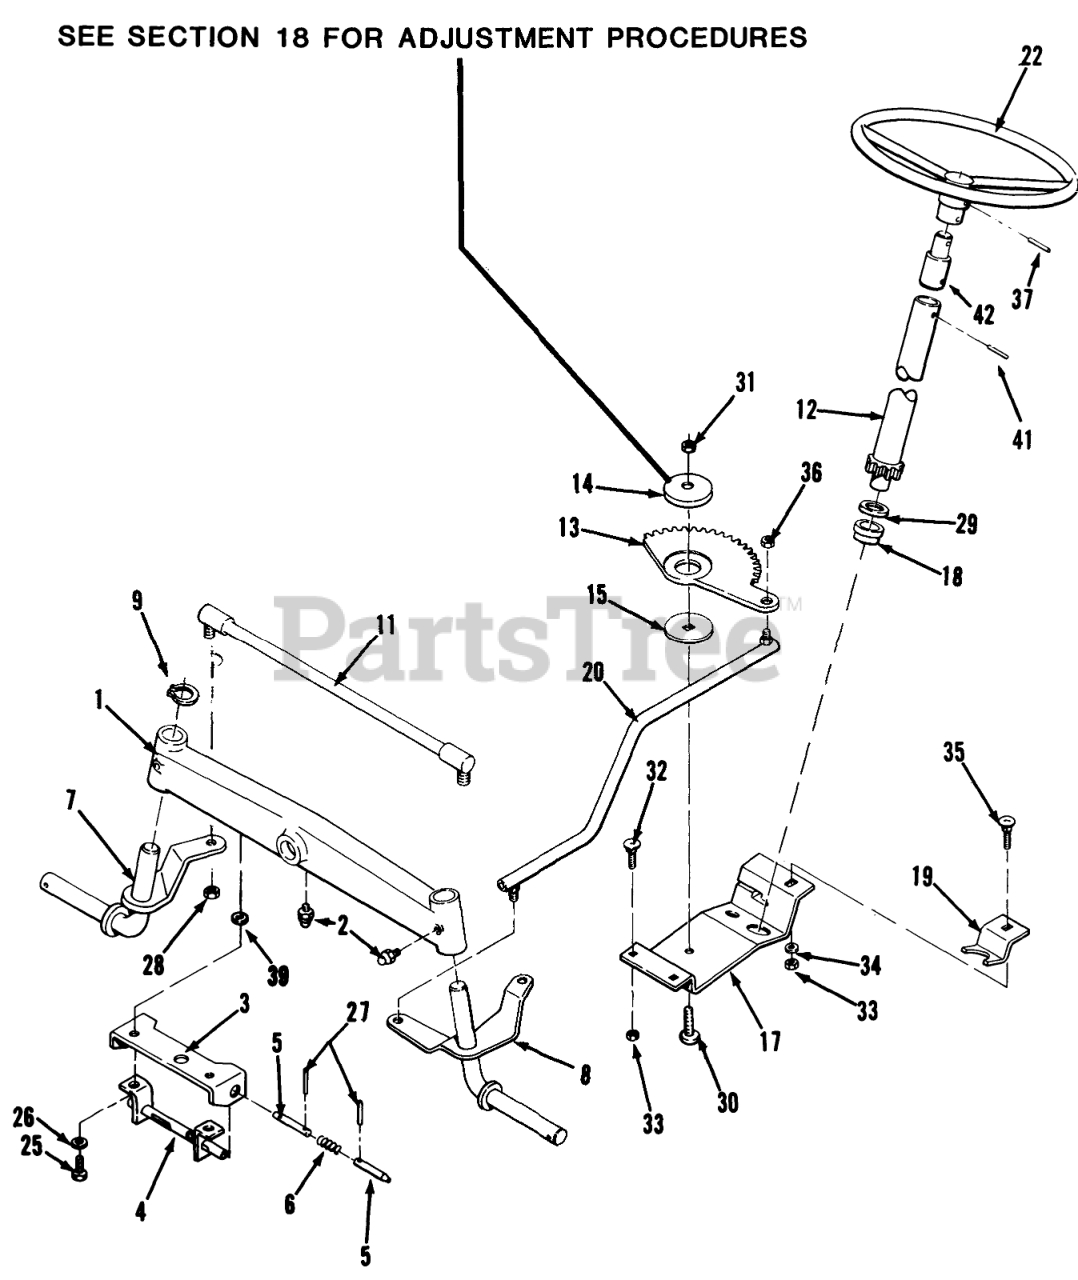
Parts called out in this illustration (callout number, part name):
1	AXLE-FRONT R
2	Zerk
3	BRACKET-SUPPORT R
4	TUBE & BRACKET ASM R
6	SPRING
7	ASSY ARM STEERING R
8	ASSY ARM STEERING R
9	Snap Ring
11	ASS'Y-TIE ROD R
12	ASSY PINION & SHA B
13	GEAR SECTOR
14	BUSHING
15	WASHER-BEARING
17	BRKT-STEERING GEA R
18	BEARING-WHEEL
19	RETAINER R (NS)
20	LINK-STEERING R
22	Steering Wheel
25	HHCS
26	Lockwasher
27	SPIROL PIN
28	5/16-24 E.S. NUT
29	SHIM-WASHER
30	Bolt-Carriage
32	Bolt
33	Nut
34	WASHER 5/16 SAE
35	Collar
36	NUT-6
37	SPIROL PIN 5/16X13/8
39	WASHER
41	Pin-Roll
42	SHAFT-COUPLER
